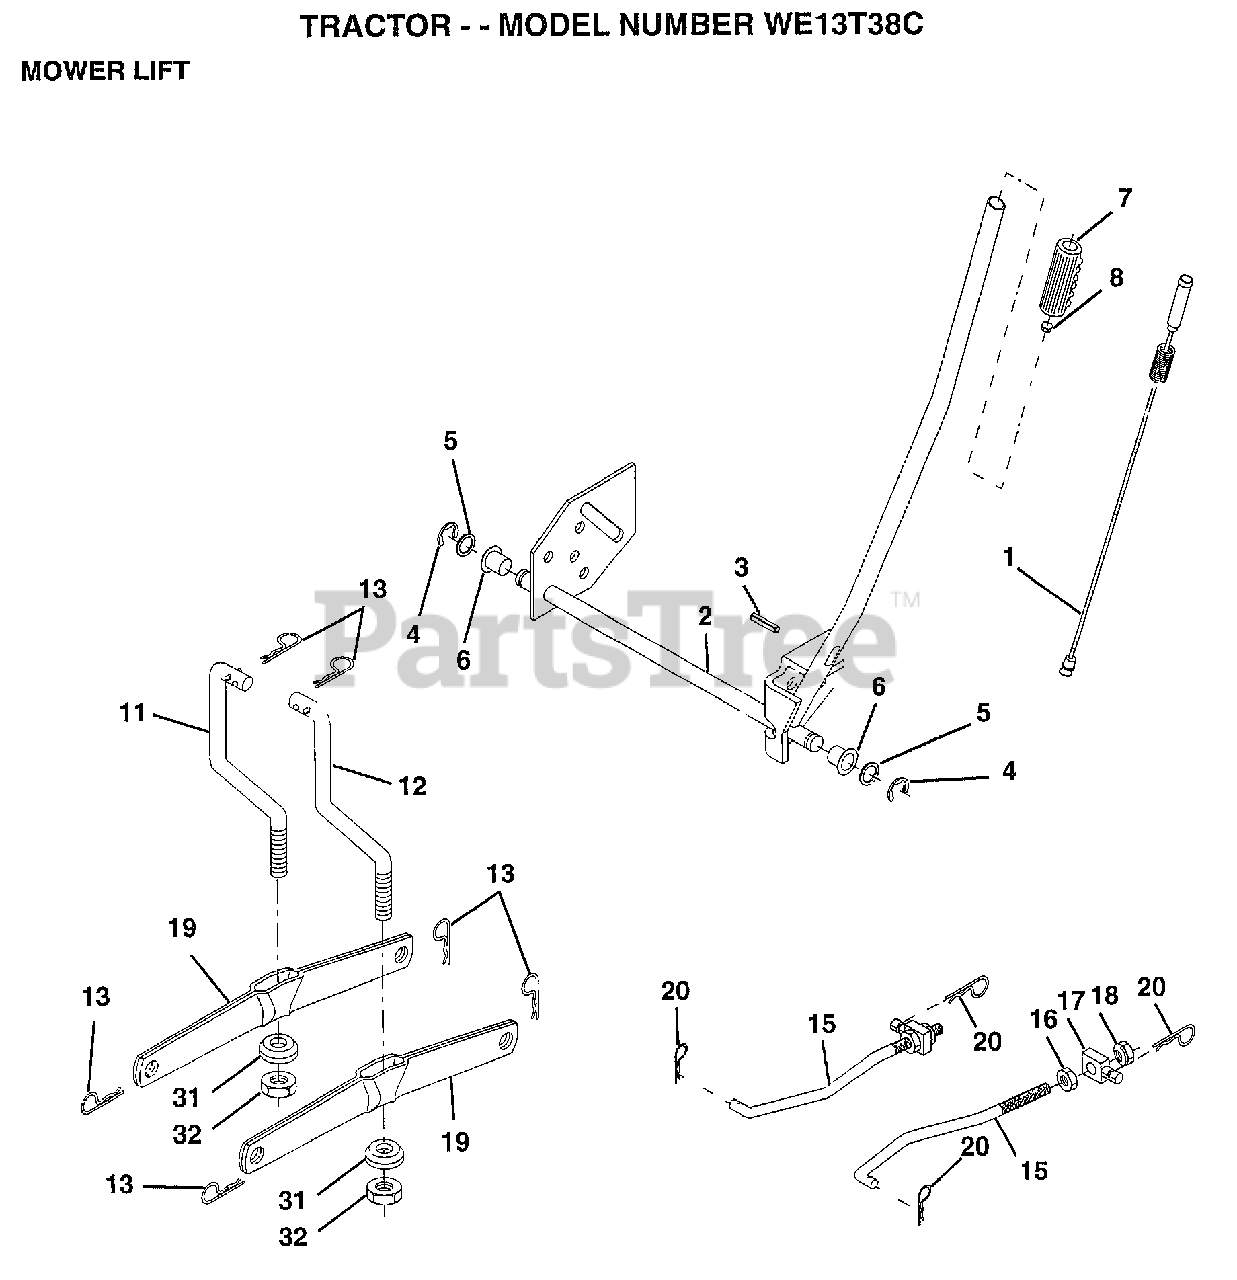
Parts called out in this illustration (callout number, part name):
1	WIRE ASM W.SPRING
2	"SHAFT ASM LIFT,RH"
3	PIN-GROOVE LT
5	WASHER
6	NYLON BEARING
7	GRIP
15	LINK.FRONT
16	NUT
17	TRUNION
18	NUT LTV
19	ARM SUSP REAR
20	RETAINER SPRING
31	BEARING PVT LH
32	NUT.CROWNLOCK.3/8
